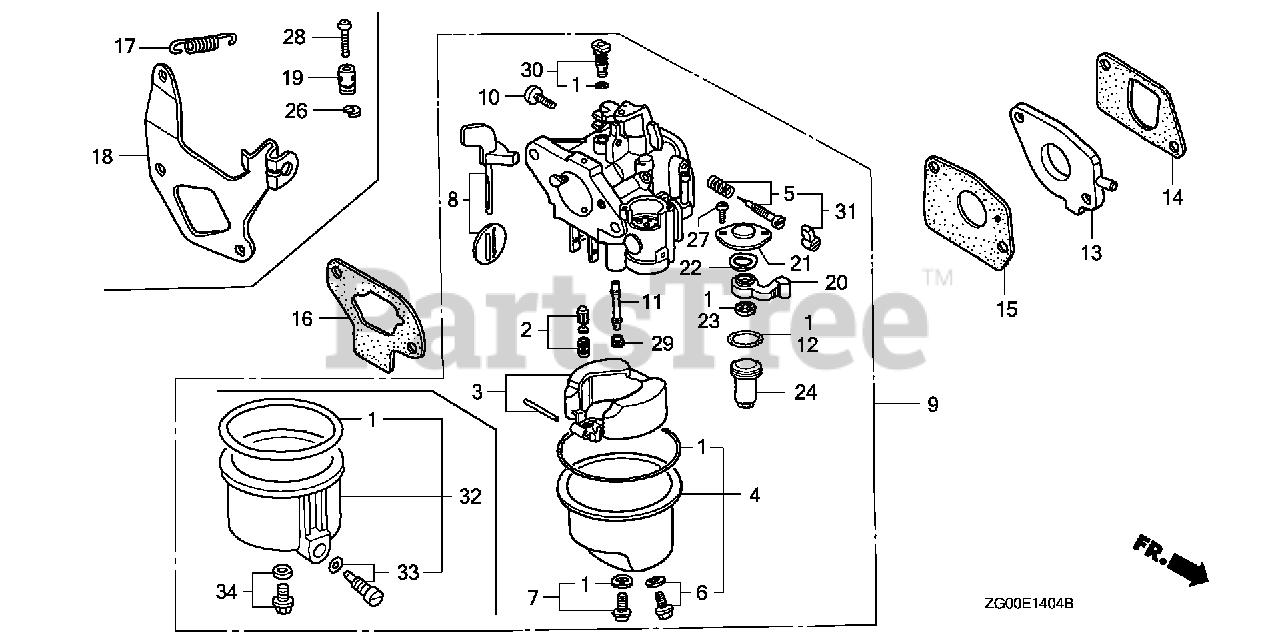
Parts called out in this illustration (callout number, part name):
1	GASKET SET (CARBURETOR NO.)
2	VALVE SET, FLOAT
4	CHAMBER SET, FLOAT (CARBURETOR NO.)
5	SCREW SET, PILOT (CARBURETOR NO.)
6	SCREW SET, DRAIN (CARBURETOR NO.)
7	SCREW SET (CARBURETOR NO.)
9	CARBURETOR ASSY. (BF11C C)
10	SCREW, THROTTLE STOP
11	NOZZLE, MAIN
13	INSULATOR, CARBURETOR
14	GASKET, INSULATOR
15	GASKET, CARBURETOR
16	GASKET, AIR CLEANER
20	LEVER, VALVE (CARBURETOR NO.)
21	PLATE, LEVER SETTING (CARBURETOR NO.)
22	SPRING, VALVE LEVER
23	GASKET, VALVE
24	CUP, FUEL STRAINER
27	SCREW, PAN (3X6)
29	JET, MAIN (#58)
29	JET, MAIN (#52)
29	JET, MAIN (#55)
30	JET SET, PILOT (#38) (CARBURETOR NO.)
30	JET SET, PILOT (#40) (CARBURETOR NO.)
